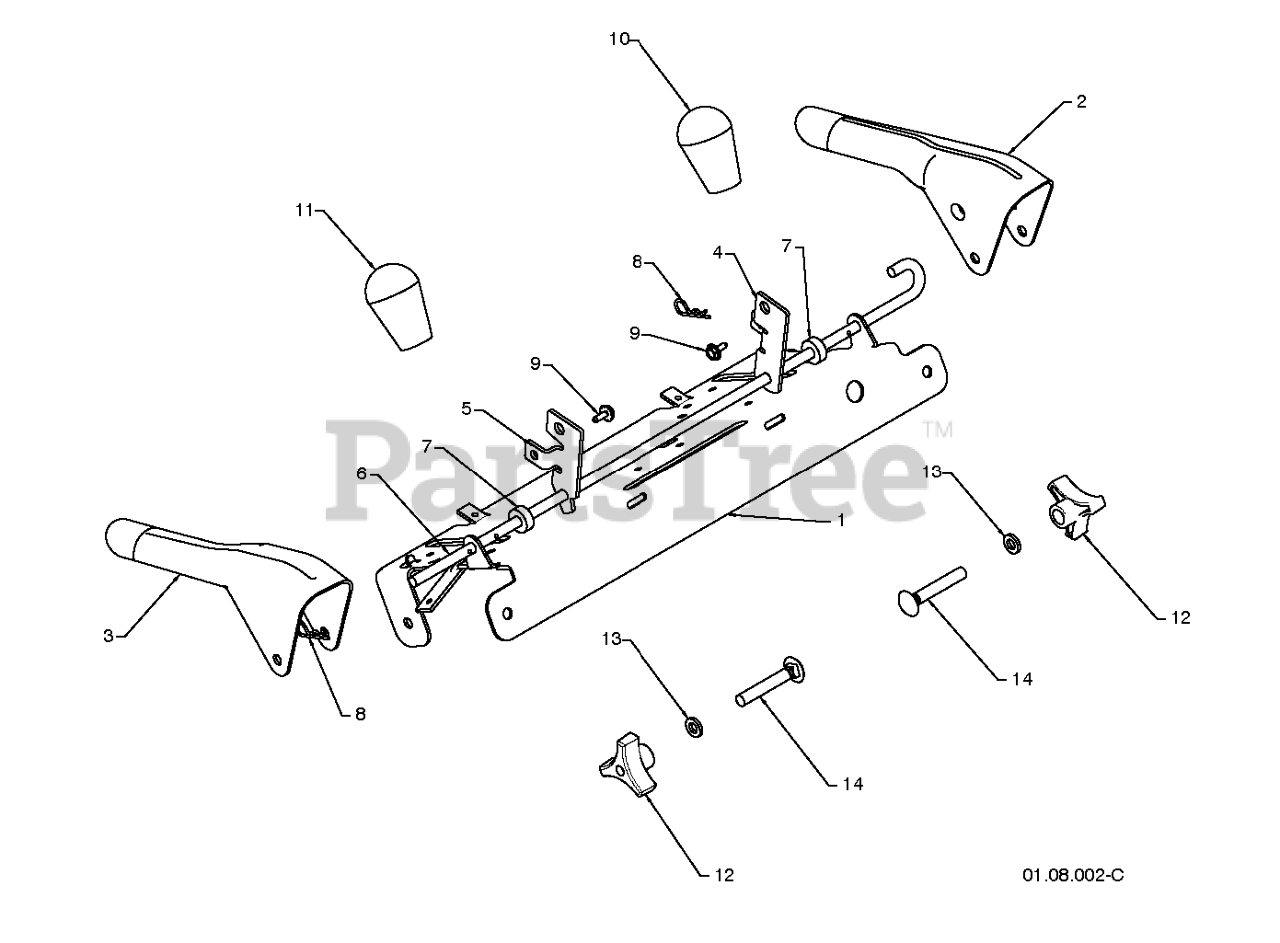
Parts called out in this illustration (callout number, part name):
1	PANEL.CONTROL.PNT.BLACK
2	LEVER.CONTROL.LH.PNT
3	LEVER.CONTROL.RH.PNT
4	ARM.TRACTION.ROD.YZ
5	ARM.IMPELLER.ROD.
6	BAIL.CONTROL.INTERLOCK
7	SPACER CONTROL LEVER
8	SPRING RETAINER
10	KNOB LEVER, BLACK
11	RED KNOB SHIFTER
12	KNOB.HANDLE.3/8.TRI-POINT.BLAC
13	WASHER
14	BOLT 3/8-16 X 2-1/4
